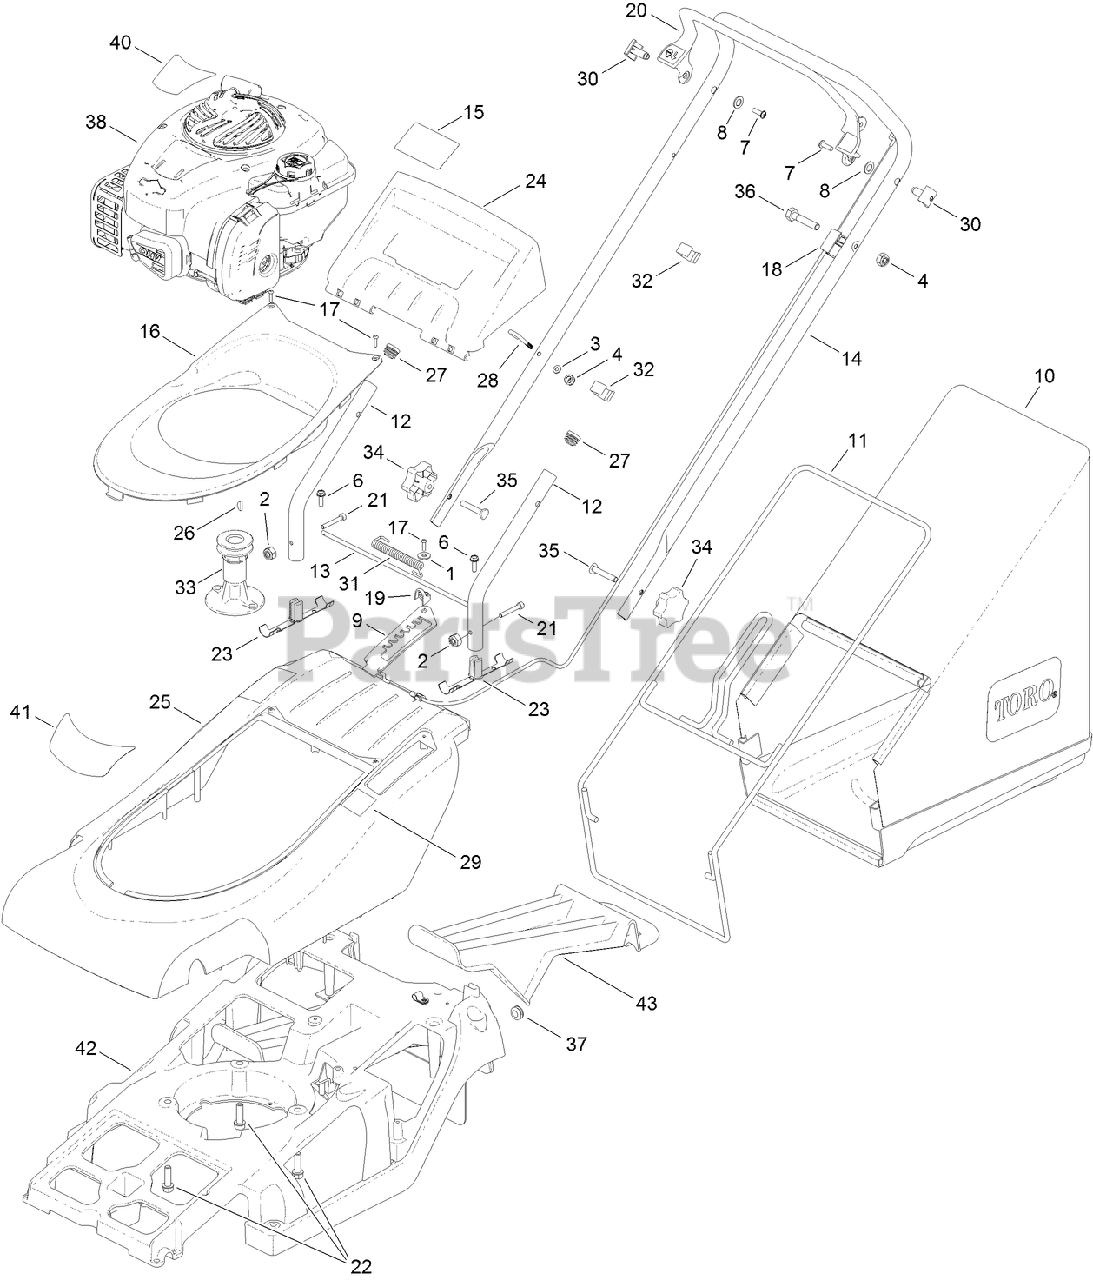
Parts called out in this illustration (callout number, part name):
1	WASHER
2	NUT-NYLOC
3	WASHER-PLAIN
4	NUT-NYLOC
6	SCREW-TAPTITE
7	SCREW
8	WASHER-NYLON
9	PLATE-HOC
10	GRASSBAG
13	BAR-HINGE
14	HANDLEBARS
15	DECAL-SAFETY
16	MOULDING-TRIM
18	CABLE-BRAKE, ENGINE
19	CLIP-P
22	SCREW-TAPTITE
23	PLUG-HANDLEBAR
24	MOULDING-DEFLECTOR, REAR
25	TOP-COVER
26	KEY-WOODRUFF
27	PLUG-TUBE
28	GUIDE-ROPE
29	DECAL-HOC
30	PIN-PIVOT
31	SPRING-DEFLECTOR
32	GUIDE-CABLE
33	CARRIER-BLADE
34	KNOB-HANDLEBAR
35	BOLT-HANDLEBAR
36	SCREW-HH
37	GROMMET-RUBBER
40	DECAL-ENGINE
41	DECAL-RECYCLE
43	PLUG-MULCHING
